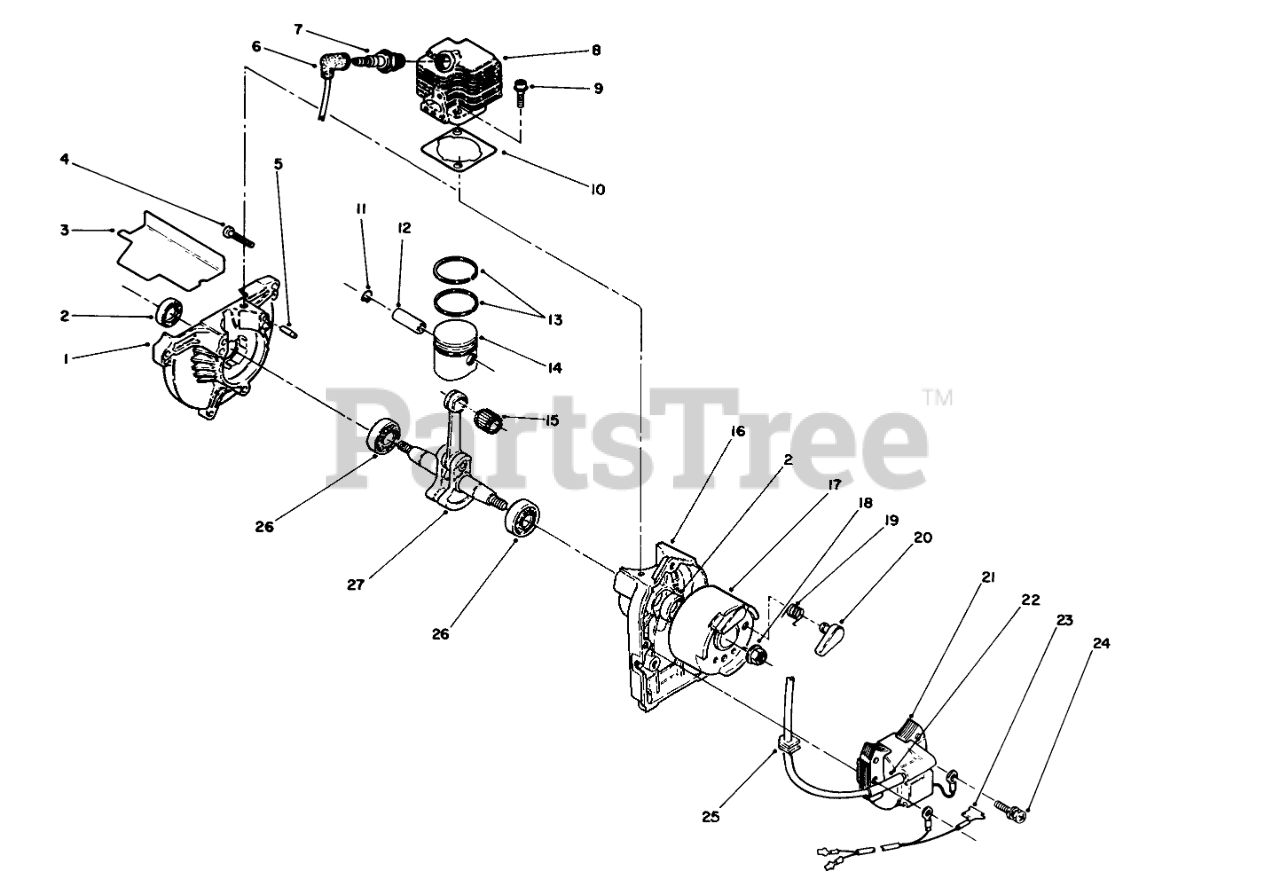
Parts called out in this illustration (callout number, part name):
1	DRIVE CASE
2	OIL SEAL
3	BAFFLE GASKET
4	Screw
6	PLUG BOOT
7	Plug-Spark
8	CYLINDER
9	FLANGE BOLT
10	CYL GASKET
11	PISTON PIN CLIP
12	Pin-Piston
13	TOP RING
14	Piston Assembly (Incl. Ref. #11 & 12)
15	NEEDLE BEARING
16	STARTER CASE
17	Flywheel (Incl. Ref. #19 & 20)
19	RETURN SPRING
20	RATCHET
21	IGNITION COIL
23	LEAD WIRE
24	BOLT AND WASHER
25	GROMMET
26	BEARING
27	CRANKSHAFT ASSEMBLY
